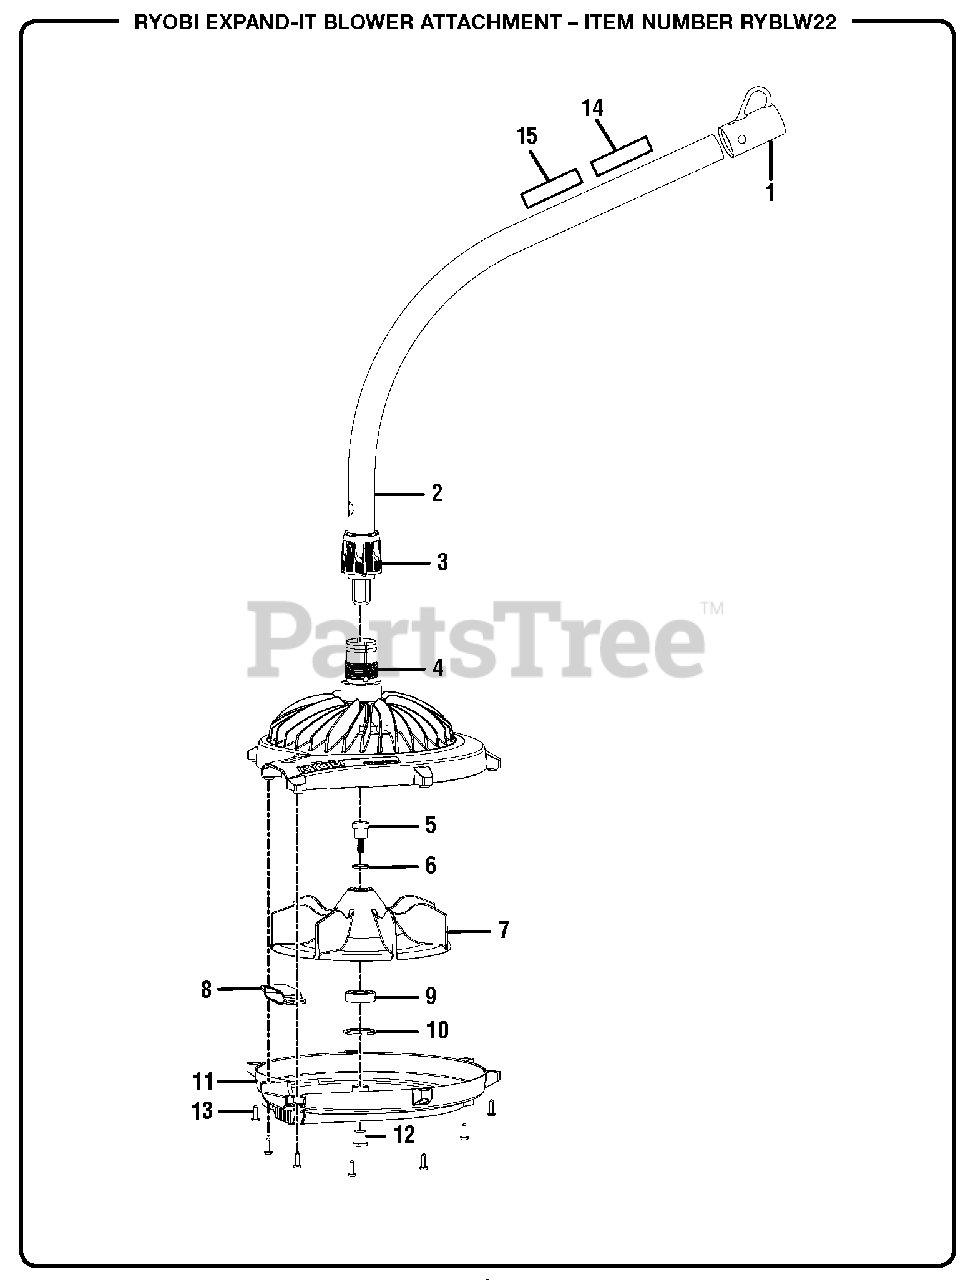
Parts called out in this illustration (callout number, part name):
1	Hanger Cap
2	Blower Attachment Shaft
3	Attachment Securing Cap
4	Upper Housing
5	Shoulder Bolt (M5 x 21 mm)
6	Lock Washer (M12)
7	Fan
9	Ball Bearing (6001-zz)
11	Lower Housing
12	Threaded Insert
13	Screw (M4 x 13 mm, T.F.)
14	Warning Label
15	Logo Label
